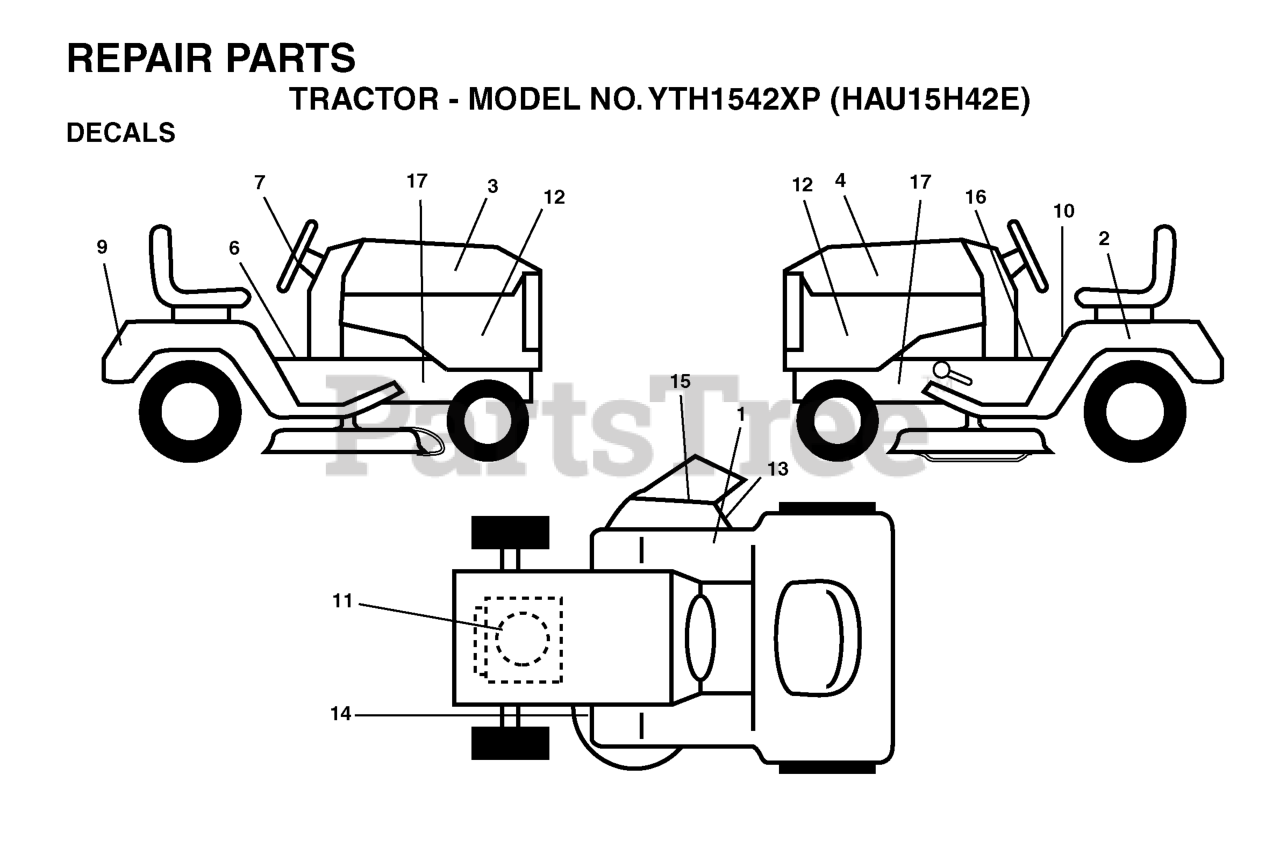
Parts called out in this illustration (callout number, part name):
1	DECAL
2	DECAL BTRY SYMBOLS
3	DECAL HOOD RH
4	DECAL HOOD(L)YTH1542XP
6	DECAL PARK BRAKE
7	DECAL.WHEEL.STEERING.HUSQ.PERM
9	DECAL, FENDER
10	DECAL READ OWNER'S MAN SYMS
12	DECAL HOOD SIDES
13	DECAL.INTERNATIONL.CUTFINGER
14	DECAL V BELT SCHEMATIC
15	DECAL DECK "B" 42"
16	DECAL
